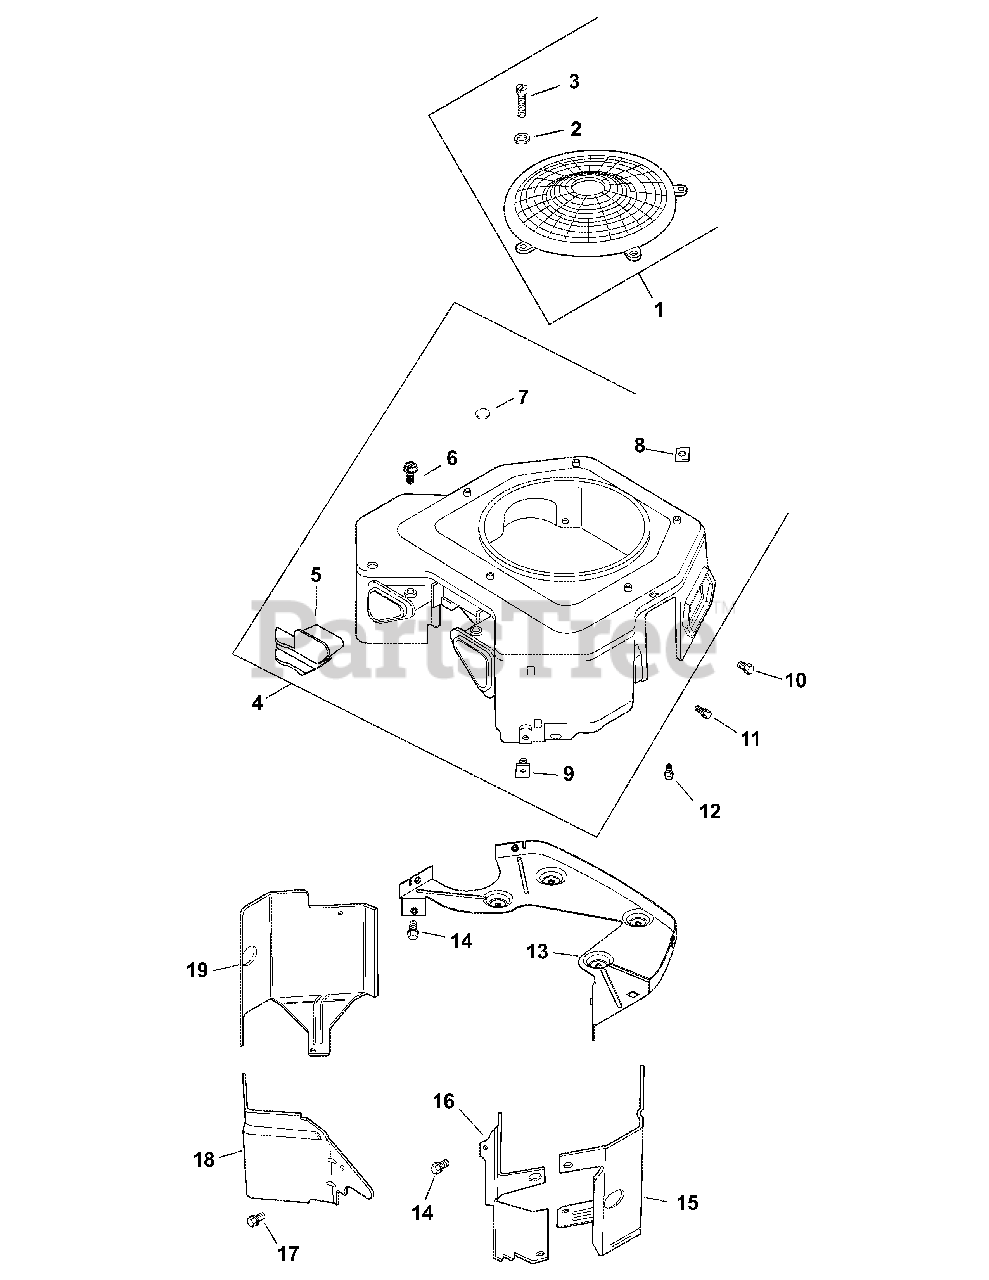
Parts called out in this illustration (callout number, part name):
1	Kit, Blower Housing Assembly
2	Nut, Plastic
3	Cover, Blower Housing
4	Screw, Wsh Hd Tap #8-18 x 1/2"
5	Plug, Button 9/16
7	Kit, Fixed Guard
9	Screw, FLG THD FRM M5 x .8 x 16
10	Screw, FLG THD FRM M5 x .8 x 16
11	Screw, FLG THD FRM M5 x .8 x 20
12	Kit, Backing Plate
13	Screw, FLG THD FRM M6 x 1.0 x 16
14	Baffle, Cyl Barrel #2 Side
15	Baffle, Valley-#2 Side
16	Screw, FLG THD FRM M5 x .8 x 10
17	Baffle, Valley #1 Side
18	Baffle, Cyl Barrel - #1 Side
